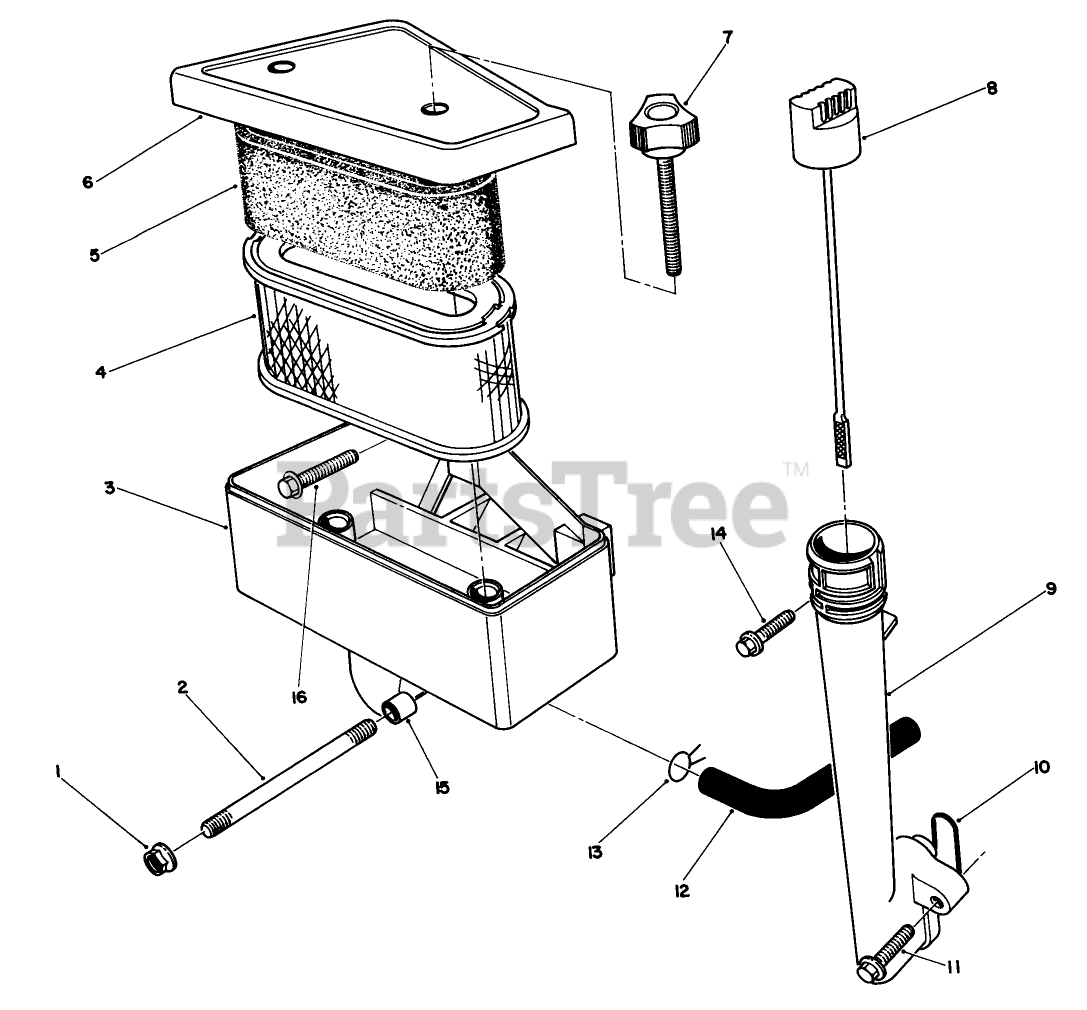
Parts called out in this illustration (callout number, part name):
3	AIR CLEANER BODY
4	AIR FILTER ELEMENT
5	Filter-Foam
6	AIR CLEANER COVER *B
7	RETAINER - COVER
10	O-RING
13	CLAMP F/W ENGINE
15	SPACER
